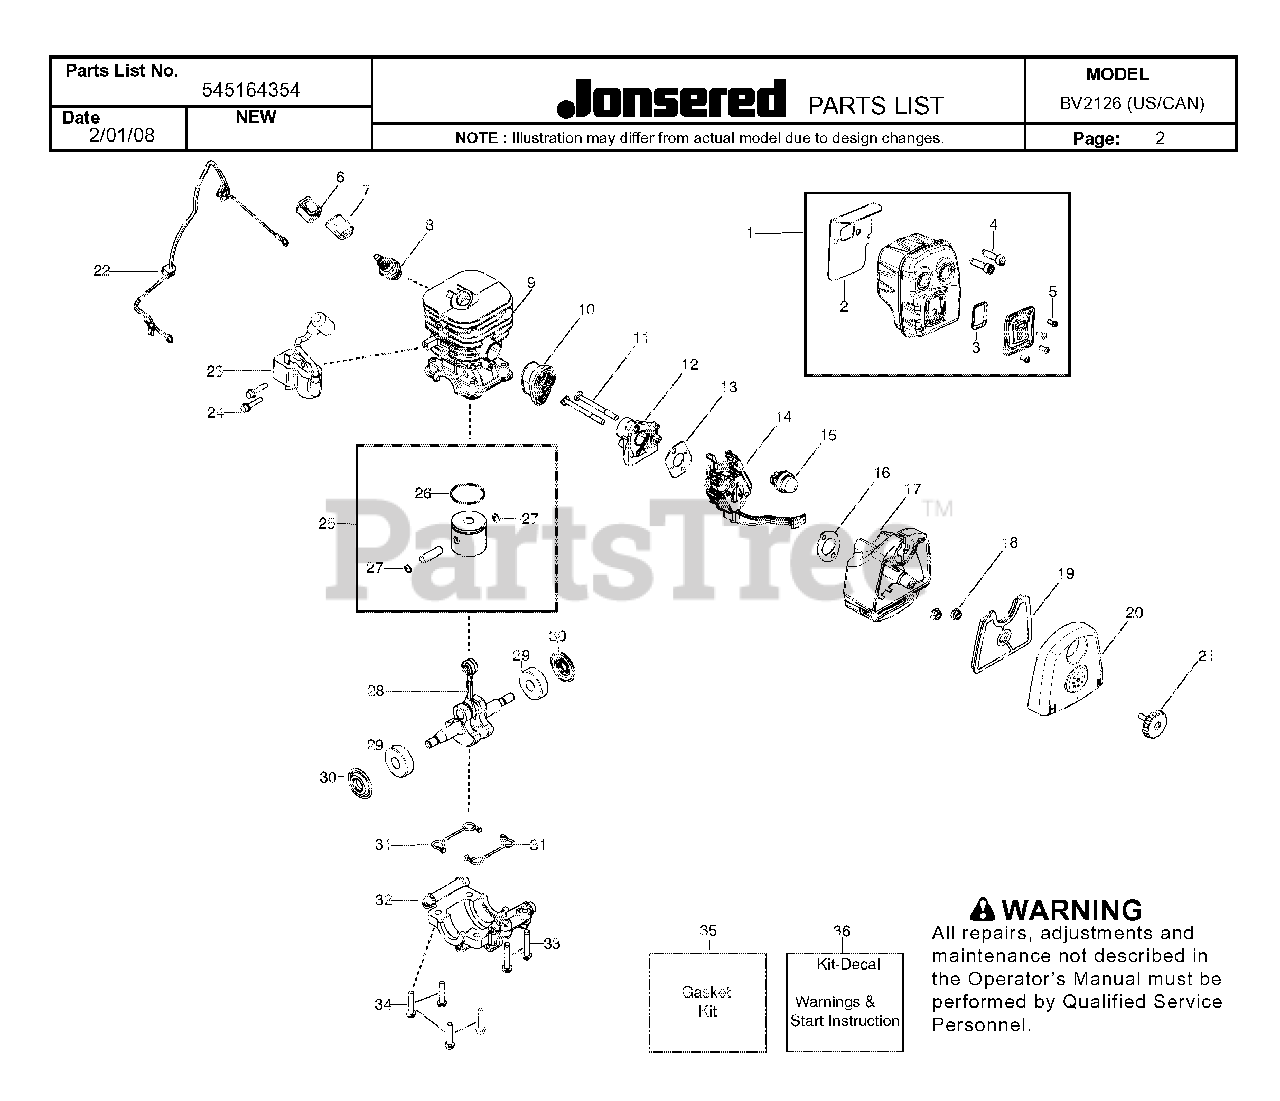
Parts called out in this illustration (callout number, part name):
1	ASSY, MUFFLER
3	KIT, SPARK SCREEN
4	BOLT MUFFLER
5	SCREW-6-19X5/16PLAST PA
6	KIT SWITCH
7	PROTECTOR, SWITCH
8	PLUG-SPARK (RCJ-6Y)
9	CYLINDER -CHROME
10	BOOT, CARB
12	PLATE, CARB
14	KIT, CARB
15	AIR PURGE
17	BASE - AIR BOX
19	FILTER, AIR
20	COVER - AIR BOX
21	ASSY - AIR BOX KNOB
22	ASSY, LEADWIRE
23	IGNITION MODULE
24	SCREW M4 X .70 TT 16MM
25	KIT - PISTON
26	RING PISTON
27	WRIST PIN RET.
28	KIT, CRANKSHAFT
29	BEARING RADIAL BALL (6201)
30	CRANKSHAFT SEAL
32	CAP - BEARING
34	B0LT, C/SHAFT 36/41
36	KIT DECAL
